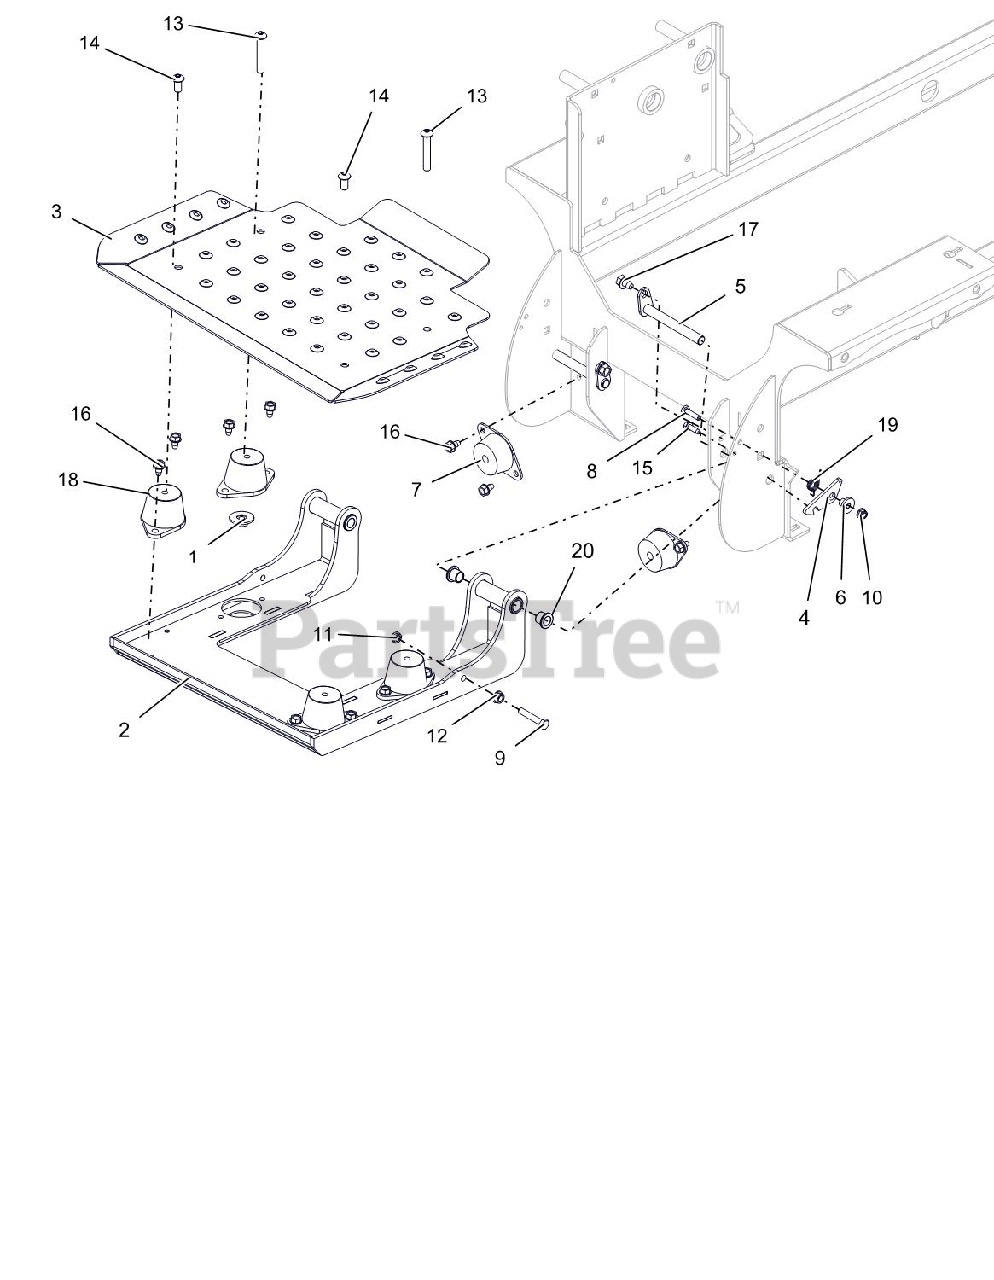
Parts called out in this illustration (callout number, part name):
1	WLDMT, SEAT RETAINER
2	WLDMT, OPERATOR PLATFORM
3	PLATE, OPERATOR PLATFORM
4	LATCH, PLATFORM
5	WLDMT, PIN
6	BUSH, FLG .26 .X .42 X .88
7	MOUNT, ENGINE, VIBRATION ISO
8	@BLT-HEX .25-20X1.00 GR5 YWZC
9	@BLT-HEX .31-18X1.75 GR5 YWZC
10	@NUT-LK-NYL-FLG .25-20 YWZC
11	@NUT-LK-CTR .31-18 YWZC
12	@NUT-SPNLK-FLG .312-18 YWZC
13	BLT-BTHD-SOCKET .38-16X2.25FTH
14	BLT-BTHD-SOCKET .38-16X.75
15	SCR-TAP-PM .25-20X.75 TR YWZ
16	@SCR-TAP .31-18X.50 HWH TR YWZ
17	@SCR-TAP .38-16X.50 HWH TR YWZ
18	MOUNT, ISOLATOR
20	BRG, FLG .500X.620X.500 BRNZ
